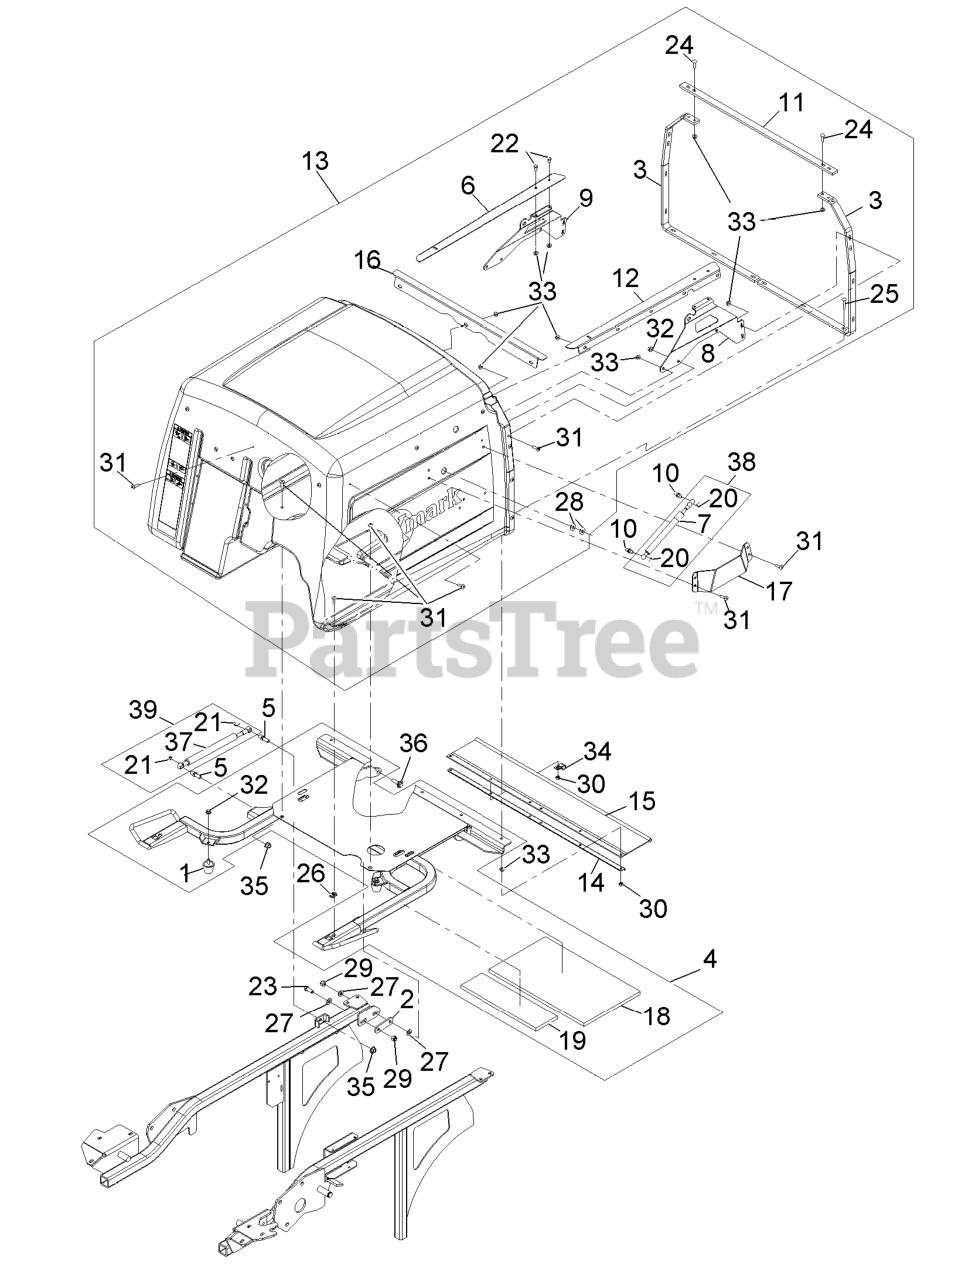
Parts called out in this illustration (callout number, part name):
1	BUMPER-RUBBER
2	ARM-LIFT, DECK
3	REINFORCEMENT-HOPPER
4	HOPPER FRAME ASM
5	STUD-BALL
6	ANGLE-SCREEN TRACK, RH
7	SHOCK-GAS TENSION
8	BRACE-DOOR PIVOT, LH
9	BRACE-DOOR PIVOT, RH
10	STUD-BALL
11	BRACKET-FRAME CONNECT
12	ANGLE-SCREEN TRACK, LH
13	ASM,HOPPER
14	CHANNEL-FRAME, HOPPER
15	DEFLECTOR-GRASS
16	CHANNEL-SCREEN, FRONT
17	PLATE-GUARD
18	INSULATION-FOAM PAD, REAR
19	INSULATION-FOAM PAD, FRON
20	CLIP-RETAINER
21	CLIP-RETAINER
22	SCREW-HH
23	SCREW-HH
24	SCREW-CARR
25	SCREW-CARR
26	Nut-Retainer-Panel 1/4-20
27	WASHER-FLAT
28	WASHER-FLAT
29	NUT-LOCK, NI
30	NUT-LOCK, NI
31	SCREW-TTH
34	CLIP-LOOM
36	SCREW-SHOULDER, HWH
37	SHOCK-COMPRESSION, GAS
38	DAMPER KIT
39	DAMPER KIT
